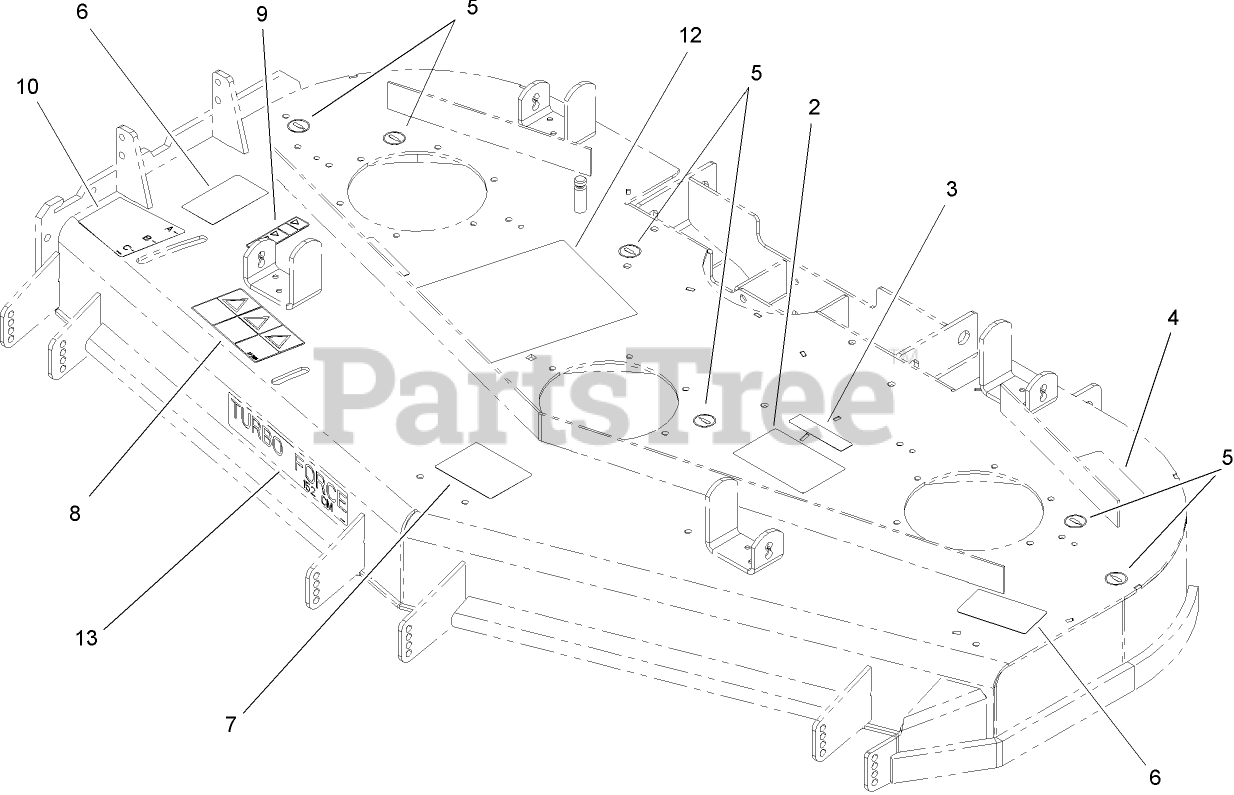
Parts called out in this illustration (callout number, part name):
2	DECAL-ROUTING, BELT
3	DECAL-WARNING
4	DECAL-TORQUE, BLADE BOLT
5	DECAL-GREASE
6	DECAL-DANGER
7	DECAL-ANTI SCALP
8	DECAL-DANGER
9	DECAL-WARNING, DEFLECTOR
10	DECAL-ADJUSTMENT, BAFFLE
12	DECAL-CHECK, SERVICE
